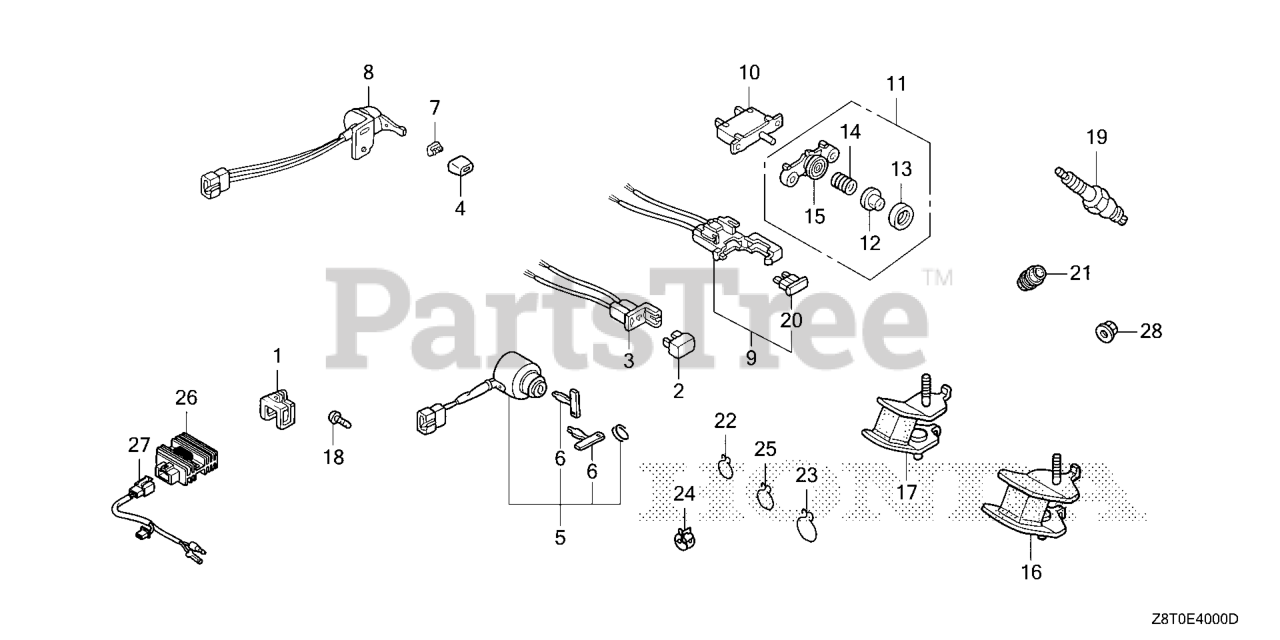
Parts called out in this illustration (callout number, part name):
16	RUBBER (LOWER)
17	RUBBER (LOWER)
21	RUBBER, FUEL (9X15X20)
22	CLIP, TUBE (B8)
23	CLIP, TUBE (B12.5)
24	CLIP, TUBE (D8)
25	CLIP, TUBE (C9)
